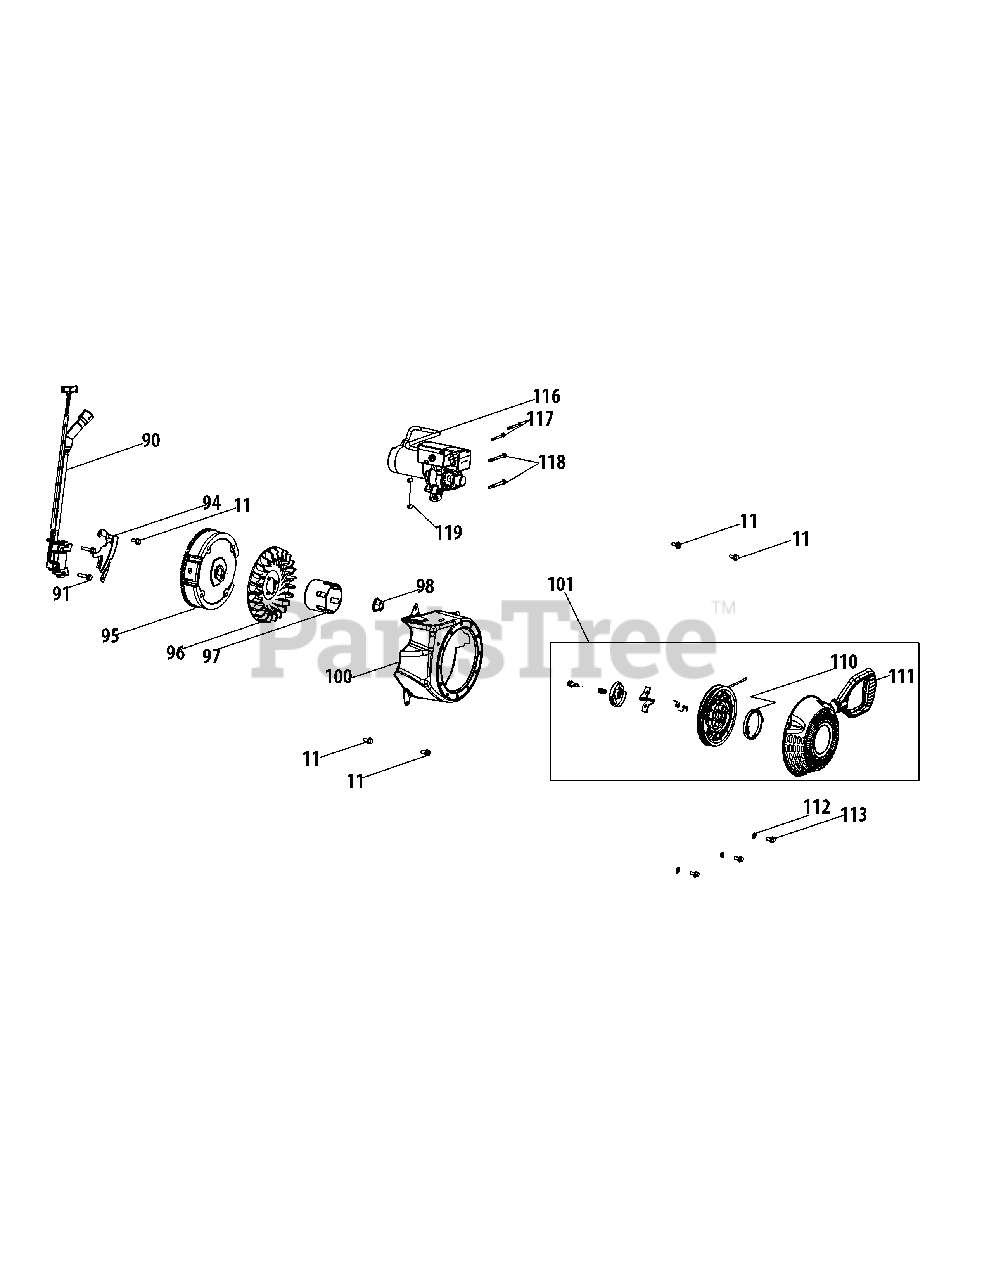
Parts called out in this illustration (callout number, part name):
11	Bolt, M6×12
90	Ignition Module
91	Bolt, M6×25
94	Lower Shield
95	Flywheel
96	Cooling Fan
97	Starter Cup
98	Nut, M14×1.5
100	Blower Housing
101	Recoil Starter
110	Recoil Spring
111	Starter Handle
112	Washer, 6
113	Bolt, M6×10
116	Electric Starter
117	Screw, M4×45
118	Bolt, M6×32
119	Pin, 8×8
